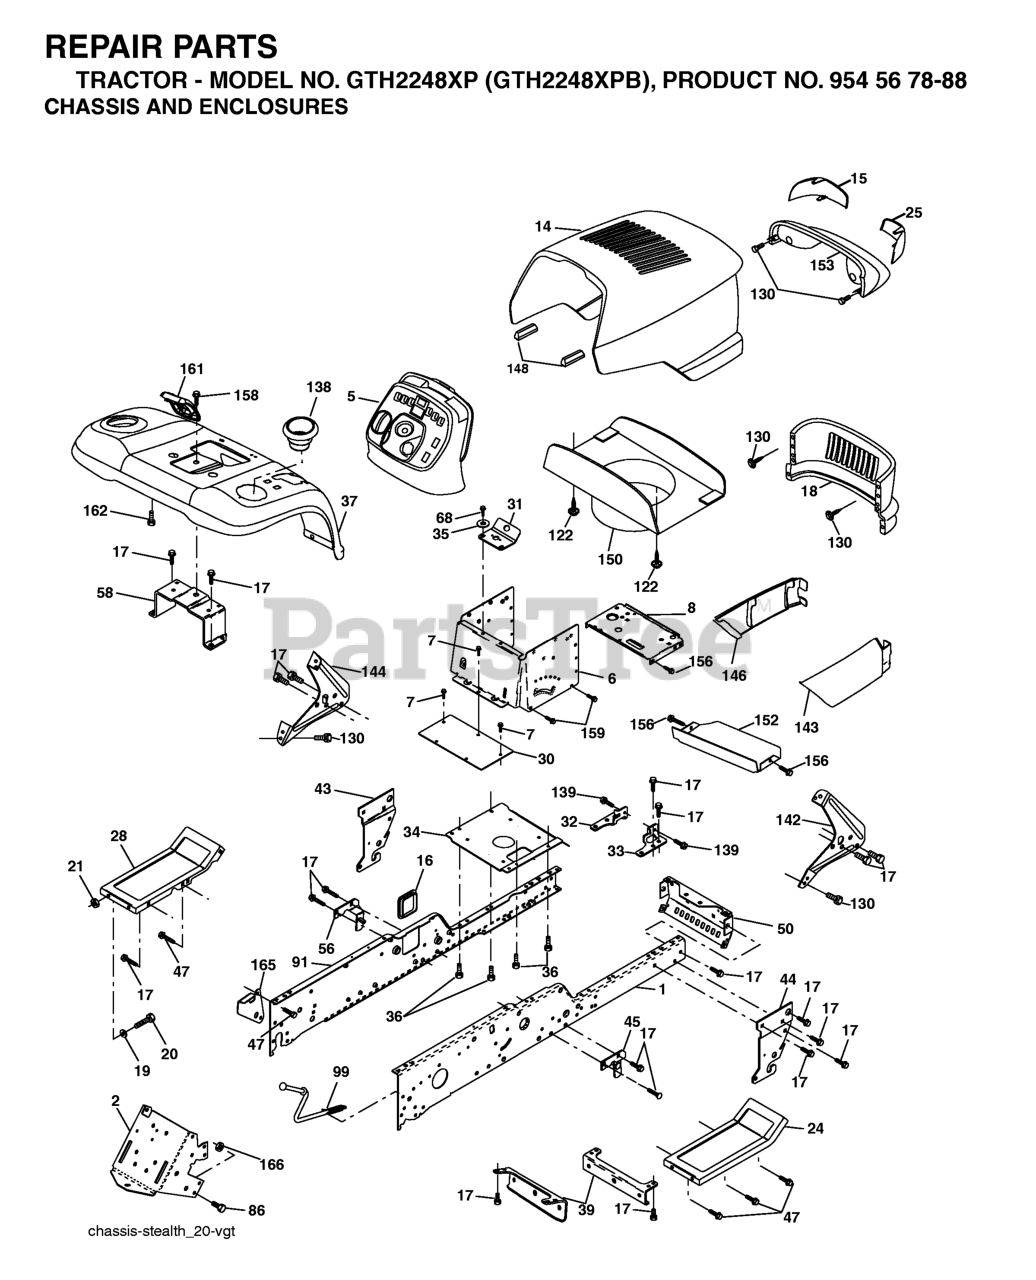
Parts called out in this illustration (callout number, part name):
1	KIT.RAIL.CHASS.RH.GT
2	DRAWBAR, GT
5	DASH, PLASTIC
6	DASH VGT, LOWER
7	SCREW
8	SUPPORT, BATTERY
14	HOOD ASM.
15	LENS LH
16	COVER ACCESS
17	SCREW 3/8-16X3/4
18	GRILLE
19	WASHER
20	BOLT
21	NUT
24	FOOTREST PNT RH
25	LENS RH
28	FOOTREST PNT LH
30	SADDLE.HYDRO.95
31	BRACKET SUPT 1-PC VGT STEERING
34	PLATE ASM ENG CHASSIS
35	WASHER
36	SCREW 5/16"
37	FENDER, PNT
39	BRACKET AXLE, FRONT
43	FRONT SUSPENSION BRKT LH
44	FRONT SUSPENSION BRKT RH
45	BRACKET, ASM., SUSP CHASSIS RH
50	BRACKET, CHASSIS FRONT
56	BRACKET ASM., SUSP CHASSIS LH
58	BRACKET ASM., FENDER
68	Screw 5/16-18 x 1/2 Hex, Self Tapping 5/16-18 x 1/2
91	KIT.RAIL.CHASS.LH.GT
99	ROD ASM, BYPASS
122	SCREW.HEX.WS.HD.8-18 X 7/8
130	SCREW
138	CUPHOLDER
139	BOLT, SHOULDER 5/16-18
142	BRACKET DASH STEALTH(R)
143	SKIRT GRILLE RH
144	BRACKET DASH STEALTH LH
146	SKIRT GRILLE LH
148	EXTRUSION BUMPER (3 2) (2 2)
150	DUCT HEAT HOOD
152	BROWNING SHIELD
153	LIGHT ASM.
156	SCREW
159	SCREW, 3/8-16X3/4
161	CONSOL.FUEL.WINDOW.BLACK
162	SCREW.HI-LO.CONSOLE
165	BRACKET SUPPORT TANK
166	Nut, Crownlock Hex 7/16-14 unc
